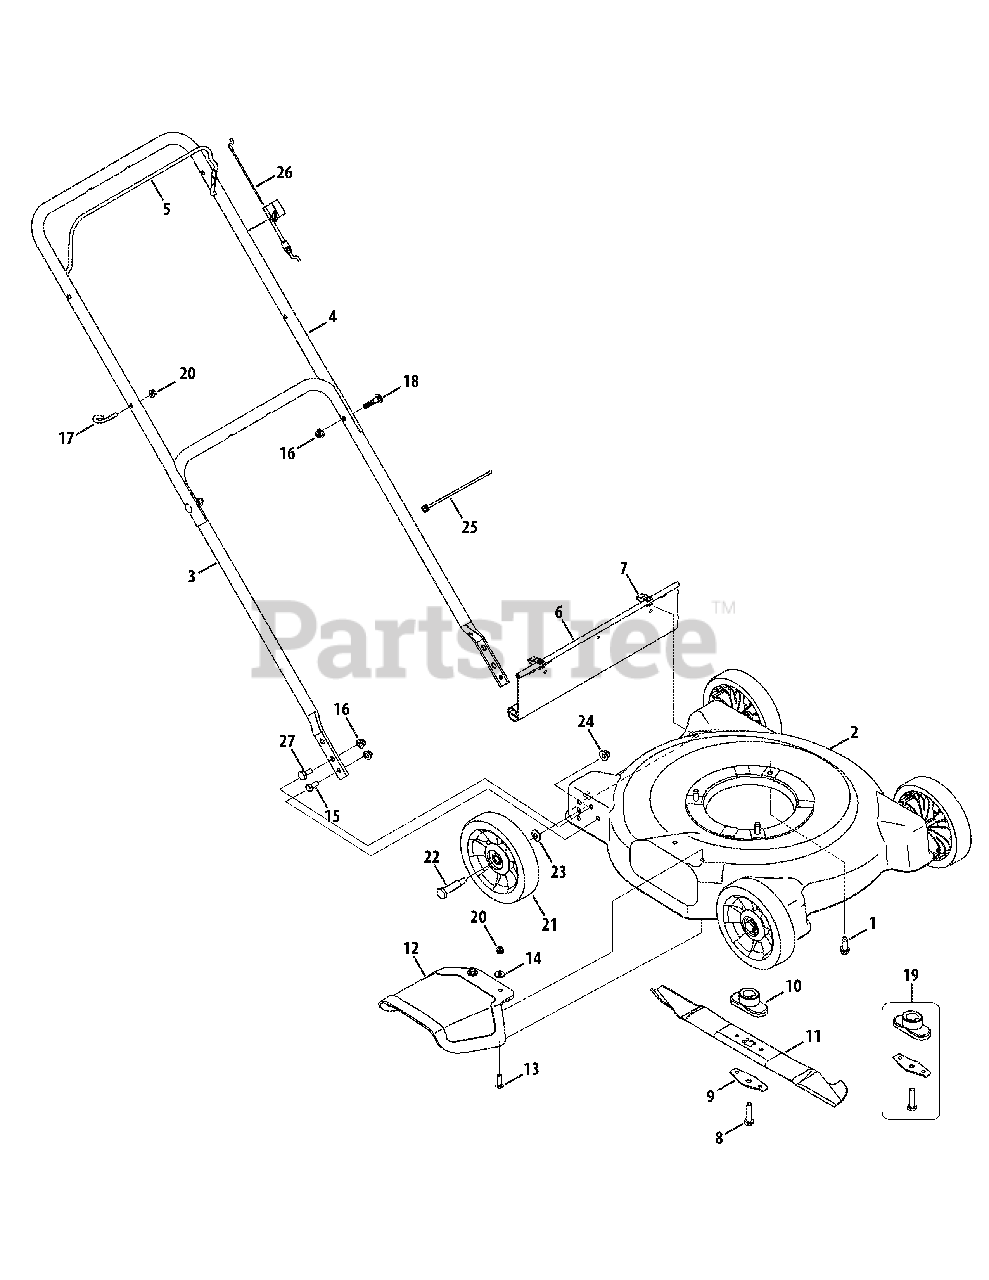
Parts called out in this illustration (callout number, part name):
1	Hex Ind. Washer Screw, 3/8-16 x 1.0
2	Cutting Deck: 20" - Red
2	Cutting Deck: 20" - Green
4	Upper Handle
5	Control Handle (Bail)
6	Rear Flap
7	Hinge Clip
8	Screw, 3/8-24 x 1.5"
9	Blade Bell Support
10	Blade Adapter
11	Cutting Blade
12	Discharge Chute
13	Carriage Screw, 1/4-20 x 1.0"
14	Flat Washer
15	Hex Screw, 5/16-18 x .75"
16	Flange Lock Nut, 5/16-18
17	Eye Bolt
18	Carriage Bolt, 5/16-18 x 1.5"
19	Blade Adapter Kit (Incl. Ref. 8-10)
20	Flange Lock Nut, 1/4-20
21	Wheel, 7" Star-Dia., Oys. Gray
22	Shoulder Screw, .498 x 1.635
23	Bell Washer
24	Flange Lock Nut, 3/8-16
25	Cable Tie
26	Control Cable
27	Shoulder Screw, 5/16-18 x.428"
